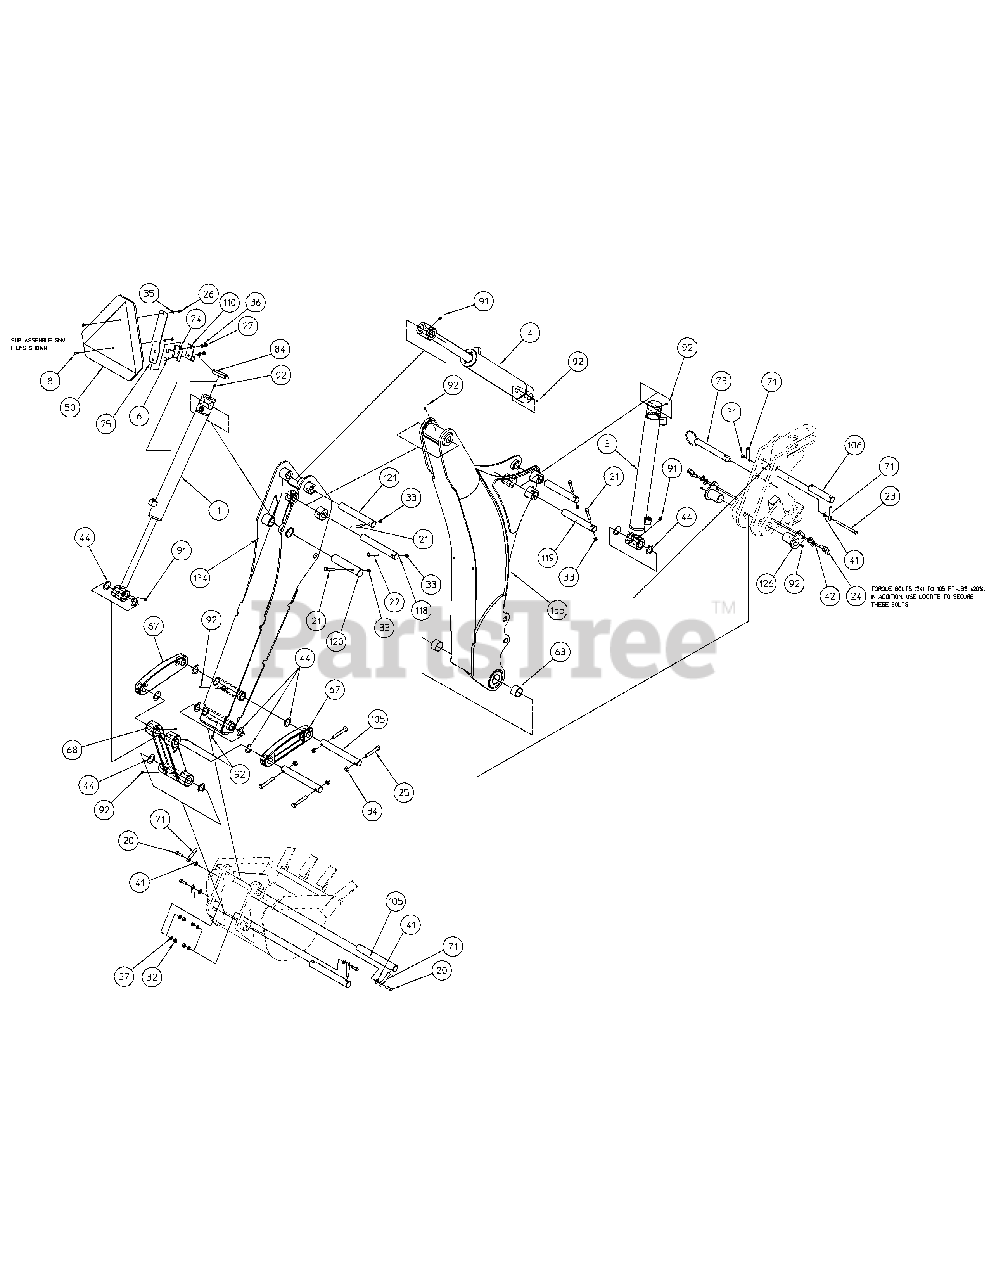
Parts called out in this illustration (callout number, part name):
1	Hydraulic Cylinder - Bucket
2	Hydraulic Cylinder - Swing
3	Hydraulic Cylinder - Boom
4	Hydraulic Cylinder - Dipper
5	Hydraulic Cylinder - Stabilizer
6	Bolt, Carriage 5/16 NC x 3/4"
7	Bolt, Carriage 5/16 NC x 1-1/4"
8	Bolt, 1/4 NC x 3/4"
9	Bolt, 5/16 NC x 3/4"
10	Bolt, 5/16 NC x 3/4" Thread Forming
11	Bolt, 5/16 NF x 3/4"
12	Bolt, 5/16 NF x 7/8"
13	Bolt, 5/16 NF x 1" Gr. 5
14	Bolt, 5/16 NF x 1.125" Gr. 5
15	Bolt, 5/16 NF x 2-1/4" Gr. 5
16	Bolt, 5/16 NF x 2.75" Gr. 8 SAE
17	Bolt, 5/16 NF x 4" Gr. 8
18	Bolt, 3/8 NF x 3/4"
19	Bolt, 3/8 NF x 1"
20	Bolt, 3/8 NF x 1-1/4"
21	Bolt, 3/8 NF x 2.5"
22	Bolt, 3/8 NF x 2-3/4"
23	Bolt, 3/8 NC x 5-1/2" Long Gr. 5
24	Bolt, 1/2 NF x 1"
25	Bolt, 1/2 NF x 3.25"
26	Nut, 1/4 NC
27	Nut, 5/16 NC
28	Locknut, 5/16 NC
29	Nut, 5/16 NF
30	Locknut, 5/16 NF
31	Locknut, 3/8 NC
32	Nut, 3/8 NF
33	Locknut, 3/8 NF
34	Locknut, 1/2 NF
35	Lockwasher, 1/4
36	Lockwasher, 5/16
37	Lockwasher, 3/8
38	Lockwasher, 3/8
39	Flat Washer, 5/16 STD
40	Washer, 5/16 SAE
41	Flat Washer, 3/8 SAE
42	Flat Washer, 1/2" Hardened
43	Machine Bushing, 1-1/2" OD x 1" ID x 18Ga.
44	Machine Bushing, 1-7/8" OD x 1-1/4" ID x 18Ga.
45	Machine Bushing, 2-1/2" OD x 1-3/4" ID x 18 Ga.
46	Cotter Pin, 3/32" Dia x 3/4"
47	Cotter Pin, 3/16" Dia x 1-1/2"
48	Cotter Pin, 1/4" Dia x 1-1/2"
49	Hair Pin Cotter, 3/64" Dia x 11/16"
51	Adapter Union, 9/16-18M x 3/8NPTF
52	Adapter Union, 9/16-18M x 3/8NPSM
53	Adapter Union, 3/4-16M x 3/8NPTF x Straight
54	Adapter Union, 3/8NPTM x 3/8NPTF x 90 degree
55	Adapter Union, 9/16-18M x 3/8NPTF x 90 degree
56	Adapter Union, 7/8-14M x 1/2NPSM x 90 degree
57	Adapter Union, 3/4-16M x 3/8NPTF x 90 degree
58	Adapter Pipe, 3/4-16NFM x 1/2NPTF
60	Coupler Nose, 3/4-16F Thread
62	Coupler Body
63	Garlock Bearing
64	Bronze Bearing
65	Garlock Bearing, 028DxR016
66	Stabilizer Pad
67	Cast Guide Link
68	Bucket Link
69	Clevis Pin, 3/16" Dia x 5/8"
70	Clevis Pin, 1/4" Dia x 7/8"
71	Pin Retainer
72	Swing Lock Pin
74	SMV Socket
75	SMV Bracket
77	Ball Joint - Shouldered
78	Ball Joint
79	Control Knob
80	Rubber Cap
81	Plastic Tie T150L
82	Plastic Tie T120L
83	Plastic Tie T50L
85	Hose Sleeve FC45-16 x 30" Long
86	Hose Sleeve FC425-16 x 19" Long
87	Hose Sleeve FC425-16 x 48" Long
88	Hose Sleeve FC425-16 x 63" Long
89	Hose Sleeve FC425-16 x 79" Long
90	Hydraulic Fluid
91	Grease Fitting
92	Grease Fitting (Two are part of #000187 Cyl.)
93	Hydraulic Hose, 3/8NPTM x 3/8NPTM x 20" long
94	Hydraulic Hose, 3/8NPTM x 3/8NPTM x 36" long
95	Hydraulic Hose, 3/8NPTM x 3/8NPTM x 80" long
96	Hydraulic Hose, 3/8NPTM x 3/8NPTM x 60" long
97	Hydraulic Hose, 3/8NPTM x 3/8NPTM x 105" long
98	Hydraulic Hose, 3/8NPTM x 3/8NPTM x 125" long
99	Hydraulic Hose, 1/2NPTM x 1/2NPTM x 54" long
100	Control Valve
101	Adapter Union, 7/16-20M x 3/8NPTF
102	Rear Shroud
103	Stabilizer Lever Control Rods
104	Control Rod
105	Buck Link Pin
106	Pivot Pin, Boom Cyl. Rod 1-1/4" Dia. x 6" Long
107	Thrust Washer
108	Stab Pivot Shaft
109	Stabilizer Cylinder Pin
110	SMV Socket Mount
111	Stabilizer Pivot Pin
112	Stabilizer Control Lever
113	Lever Bracket
114	Hose Clamp - Short
115	Upper Pivot Pin Weldment
116	Lower Pivot Pin Weldment
117	Retaning Collar
122	Swing Cylinder Pin Weldment
123	RH Pivot Weldment
124	LH Pivot Weldment
126	Pivot Pin Weldment, Boom 1-3/4" Dia. x 2-3/4" Lg
127	Swing Cylinder Pin Weldment
128	RH Toe Shield
129	LH Toe Shield
130	Cylinder Base Pin
131	Hose Clamp - Long
132	Seat Plate Weldment
133	Mainframe Weldment
134	Dipper Weldment
135	Boom Weldment
136	Swing Frame Weldment
137	Stabilizer Weldment
138	Grab Bar Weldment
139	Valve Mount Weldment
140	Front Shroud Weldment with Decals
141	RH Joystick Weldment
142	LH Joystick Weldment
144	Rubber Street Pad
145	Bolt, Hex 1/4-20 x 1.750 Gr 5
146	Bolt, Hex 1/4-20 x 2.0
147	Nut, hex 1/4-20 Gr 5 Lock
148	Flat Washer, 1/4 Hardened
149	Step Weldment
150	Adapter Union, 45 degree
